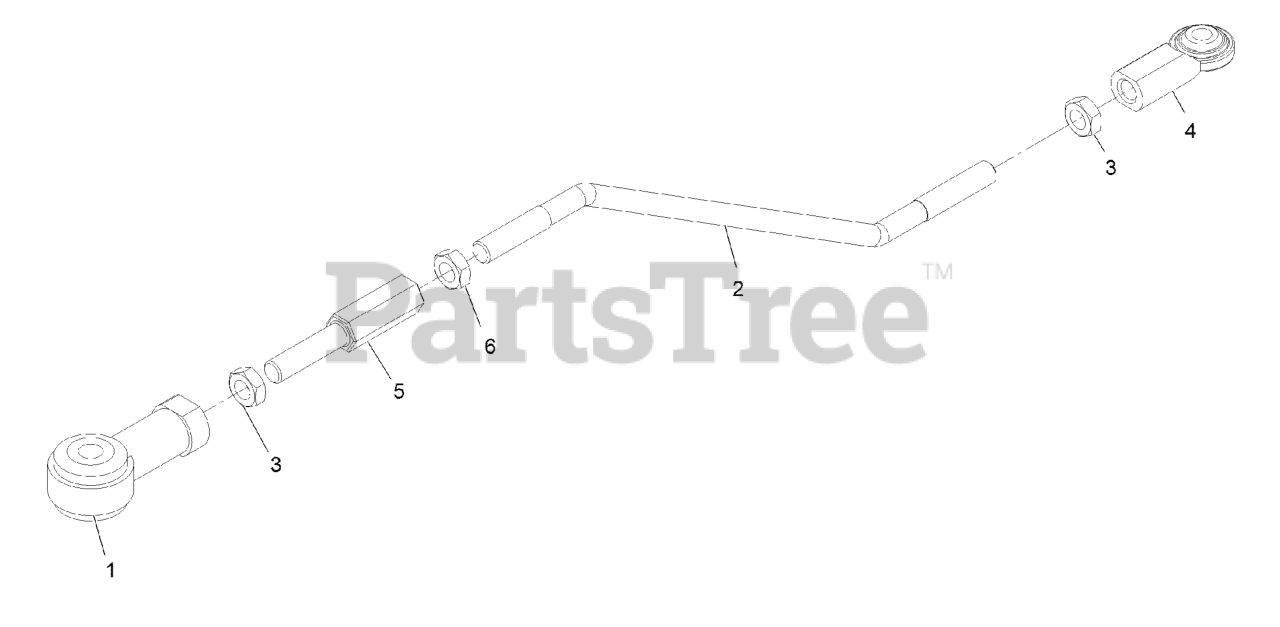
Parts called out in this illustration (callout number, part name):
1	END-ROD, ISOLATED
2	ROD-LINKAGE, REAR
3	NUT-HJ
4	JOINT-BALL, END
5	ROD-ADJUSTMENT
6	NUT-HEX JAM, LH
